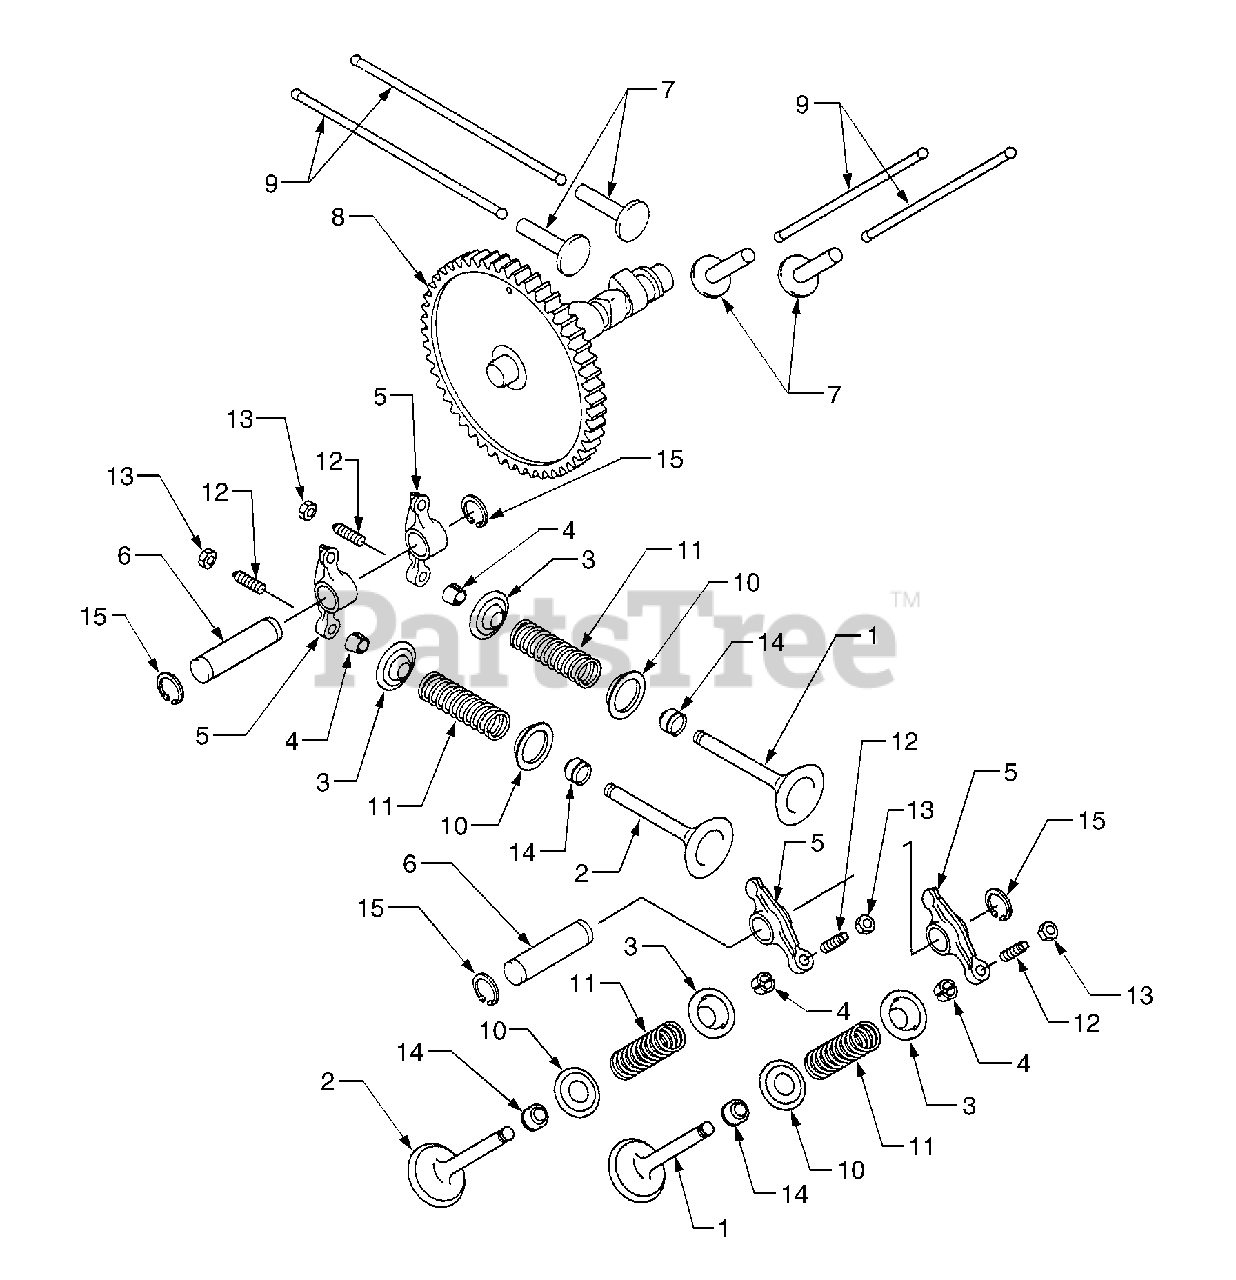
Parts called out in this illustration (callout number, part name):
1	Valve, Intake
2	Valve, Exhaust
3	Retainer, Valve Spring
6	Shaft, Rocker
8	Camshaft Assembly
10	Retainer, Spring
11	Spring, Valve
12	Screw, Valve Adjust
13	Nut, Valve Adjust Lock
